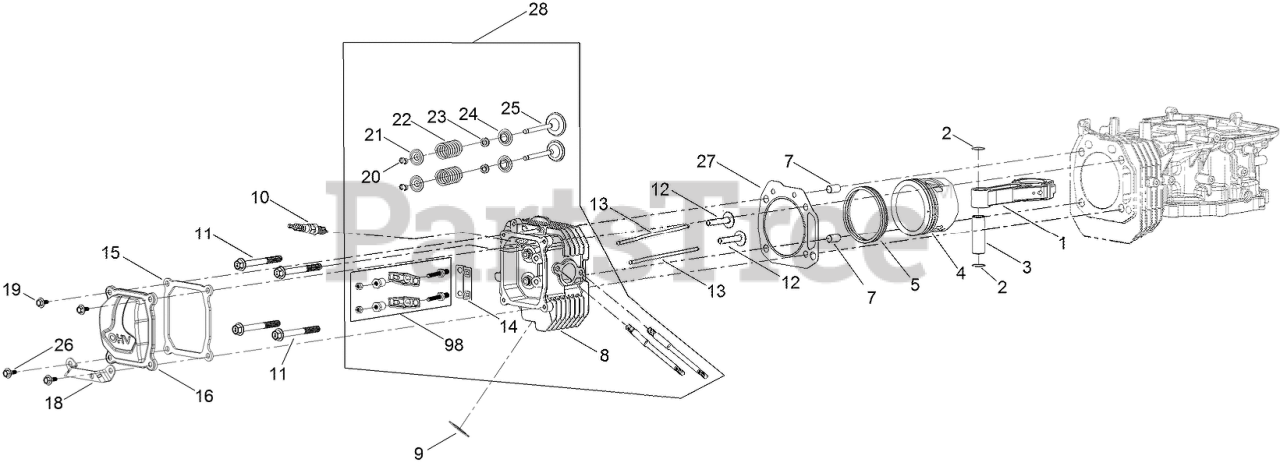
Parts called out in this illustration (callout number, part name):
1	CONNECTING ROD ASM
2	RING-RETAINING, PISTON PIN
3	PIN-PISTON
4	PISTON
5	RING SET
7	PIN-DOWEL
8	HEAD-CYLINDER
9	GASKET-EXHAUST
10	PLUG-SPARK
11	SCREW-HHF
12	LIFTER-VALVE
13	ROD-PUSH
14	PLATE-GUIDE, PUSH ROD
15	GASKET-COVER, VALVE
16	COVER-VALVE
18	BRACKET-MUFFLER
19	SCREW-SHOULDER, HHF
20	KEEPER-VALVE
21	RETAINER-SPRING, VALVE
22	SPRING-VALVE
23	SEAL-STEM, VALVE
24	SEAT-SPRING, VALVE
25	VALVE SET
26	SCREW-SHOULDER, HHF
27	GASKET-CYCLINDER
28	COMPLETE HEAD ASM
98	ROCKER ARM KIT
